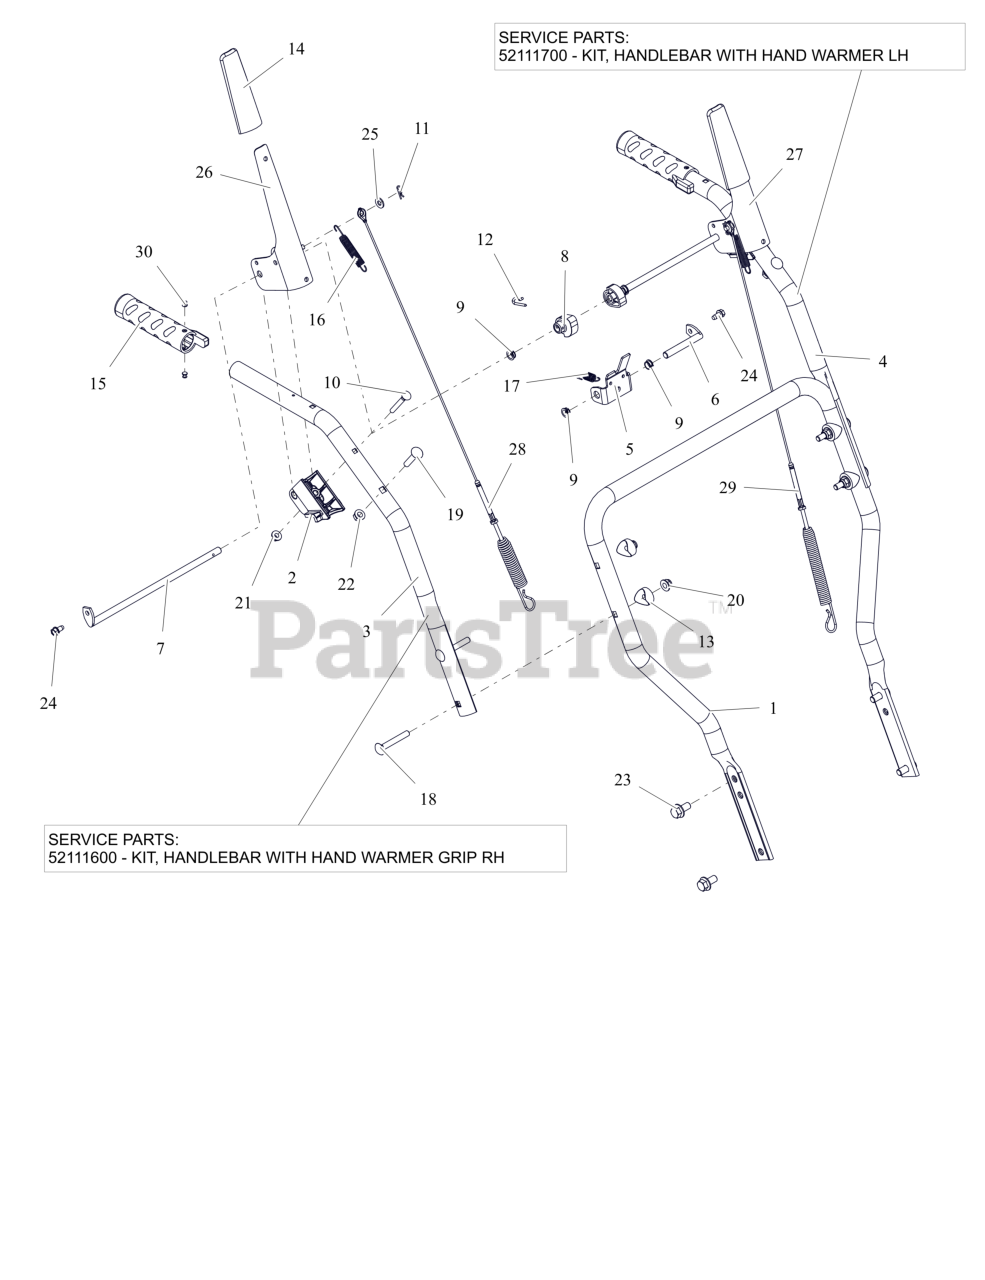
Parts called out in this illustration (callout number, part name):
1	HANDLEBAR, LOWER
2	BLOCK, CLUTCH PADDLE
3	HANDLEBAR, UPPER - RH
3	KIT, HANDLEBAR HG RH
4	HANDLEBAR, UPPER - LH
4	KIT, HANDLEBAR HG LH
5	BRACKET, INTERLOCK ARM
6	ROD, PIVOT - INTERLOCK
7	ROD, PADDLE MOUNT - PRO
8	CAM, INTERLOCK
9	BUSHING, POLYLINER-.38 SNAPIN
10	BLT-RDHDXLSQNK .25-20X2.0 G5YZ
11	PIN, HAIR #178 .06X.77 ZCC
12	PIN, SPRING CLIP
13	SPACER, HANDLEBAR
14	COVER, PADDLE
15	GRIP, HANDLE - HEATED
16	SPRING, EXTENSION
17	SPRING-EXT .047X.438X1.45
18	BLT-RHSN.31-18X2.25 G5 TBZ 120
19	BLT,RHSN .31-18X1.50 G5 ZCC
20	NUT-NYL-FLG.31-18 GF TBZ 120WR
21	NUT-LK-CTR-FLG .25-20 ZC120
22	NUT-LK-TOP-FLG .312-18 GF ZCC
24	SCR-TAP .25-20X.50 HWH ZCC
25	WSHR,FLT .281X.625X.065 ZCC
26	LEVER, CLUTCH-RH
27	LEVER, CLUTCH-LH
28	CABLE, AUGER (DELUXE & PRO)
29	CABLE, UPPER TRACTION
30	RVT-POP #43 .125X.313 STL ZINC
